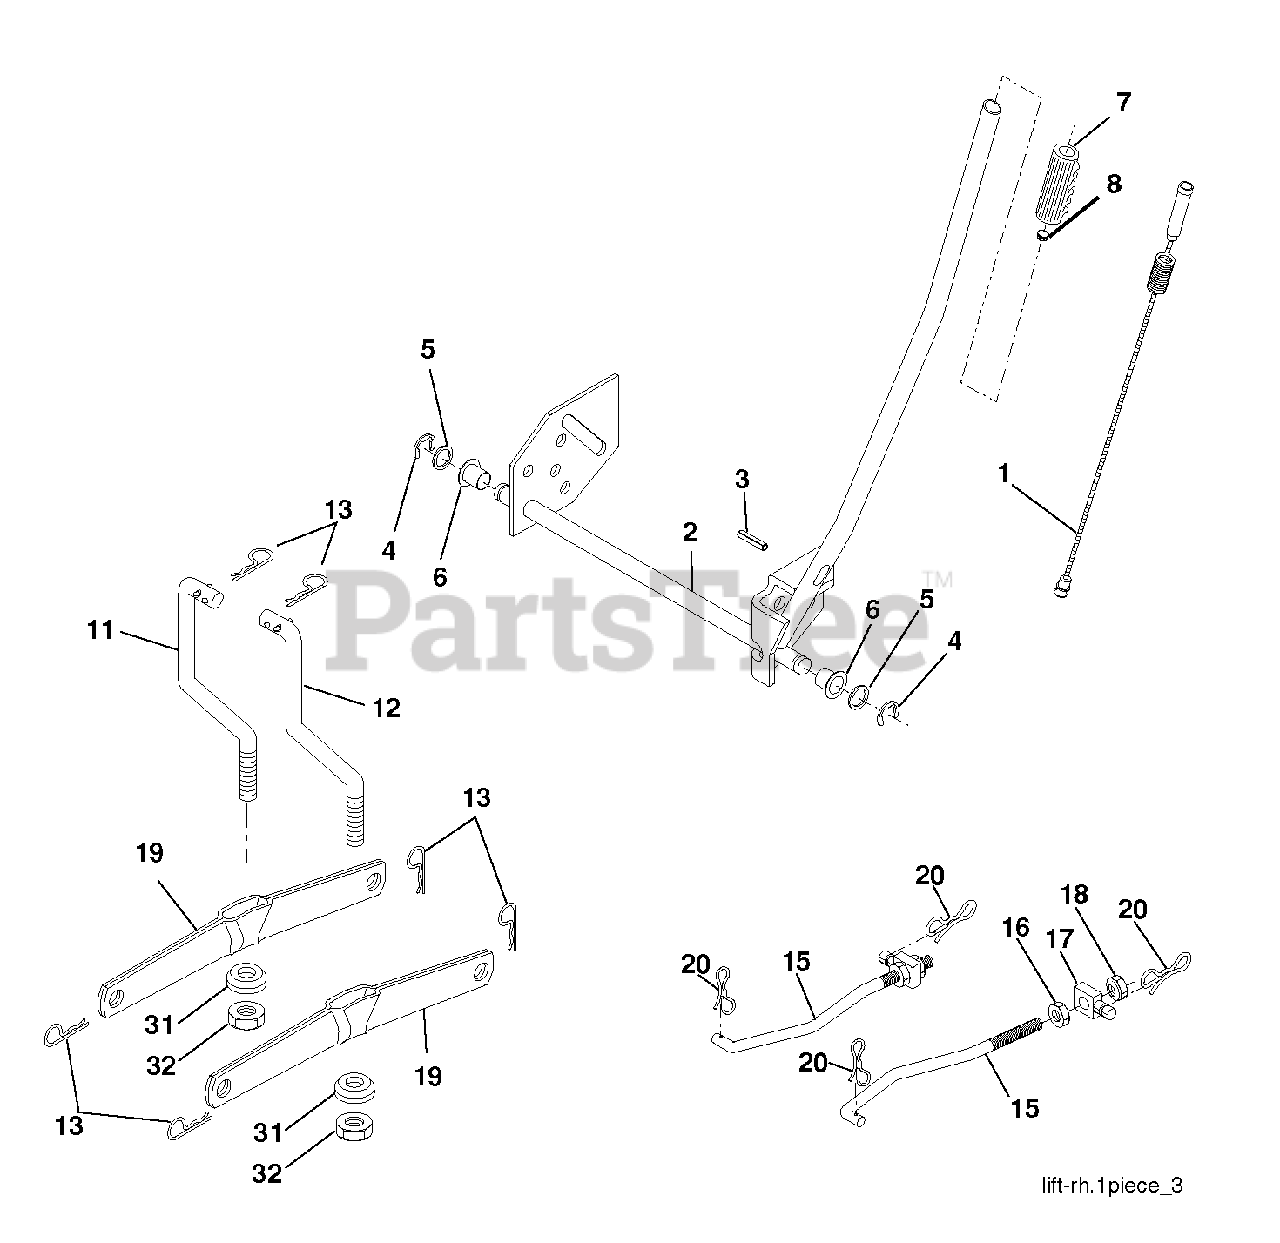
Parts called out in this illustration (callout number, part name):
1	PLUNGER.ASM.LIFT.LVR.BLK.17.32
2	SHAFT ASM R HANDLE
3	PIN GROOVE.
4	RETAINING RING LT
6	BEARING.NYLON
7	GRIP HANDLE
8	PLUNGER BUT KIT
11	LINK LIFT LH
12	Lift Link Assembly, RH
13	RETAINER-SPRNG RB
15	LINK.SUSPENSION.FRONT
16	NUT.HEX.JAM.1/2-13
17	TRUNNION
18	NUT.LK.W/WSH.1/2.
19	ARM.REAR.SUSPENSION
20	PIN.COTTER.7/16.BOW TI.
31	BEARING.PIVOT.LIFT
32	NUT CROWNLOCK 3/8-24
